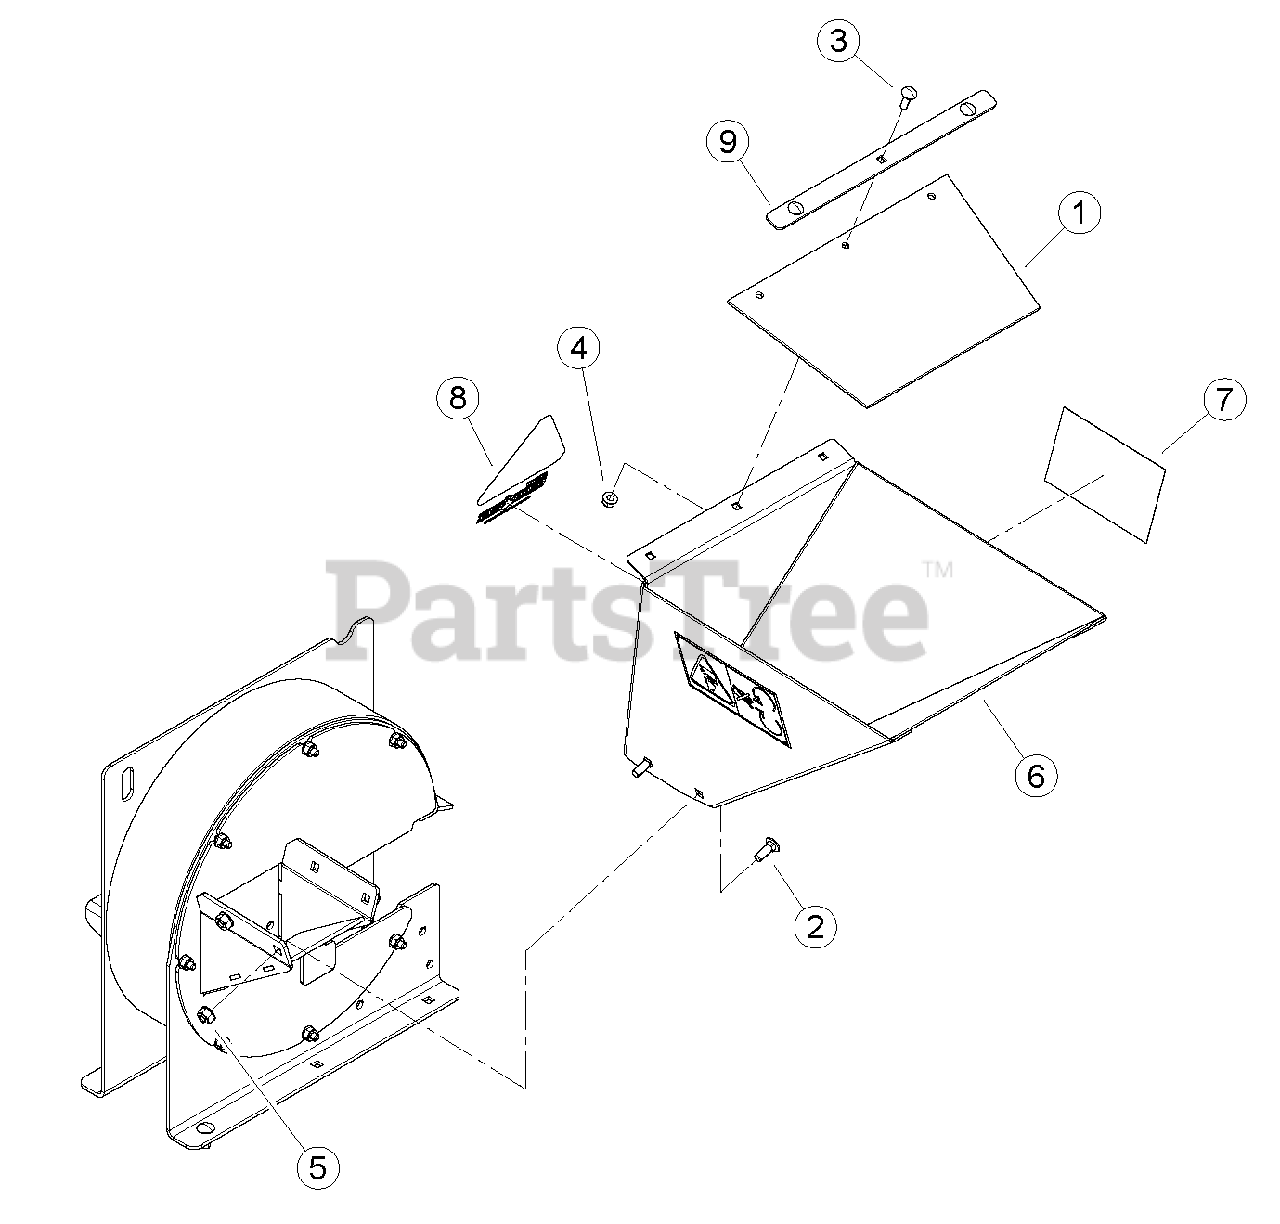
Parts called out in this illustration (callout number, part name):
1	FLAP, CHIPPER CHUTE
2	BOLT, 3/8-16 X 1 GR5 CRG
3	BOLT, 5/16-18 X 1 GR5 CRG
4	NUT, 5/16-18 NYLOCK FLANGE
5	NUT, 3/8-16 NYLOCK FLANGE
6	ASSEMBLY, INFEED CHUTE
7	DECAL, BLADE DANGER ISO
8	DECAL, CHIP IT
9	STRIP, FLAP RETAINER
